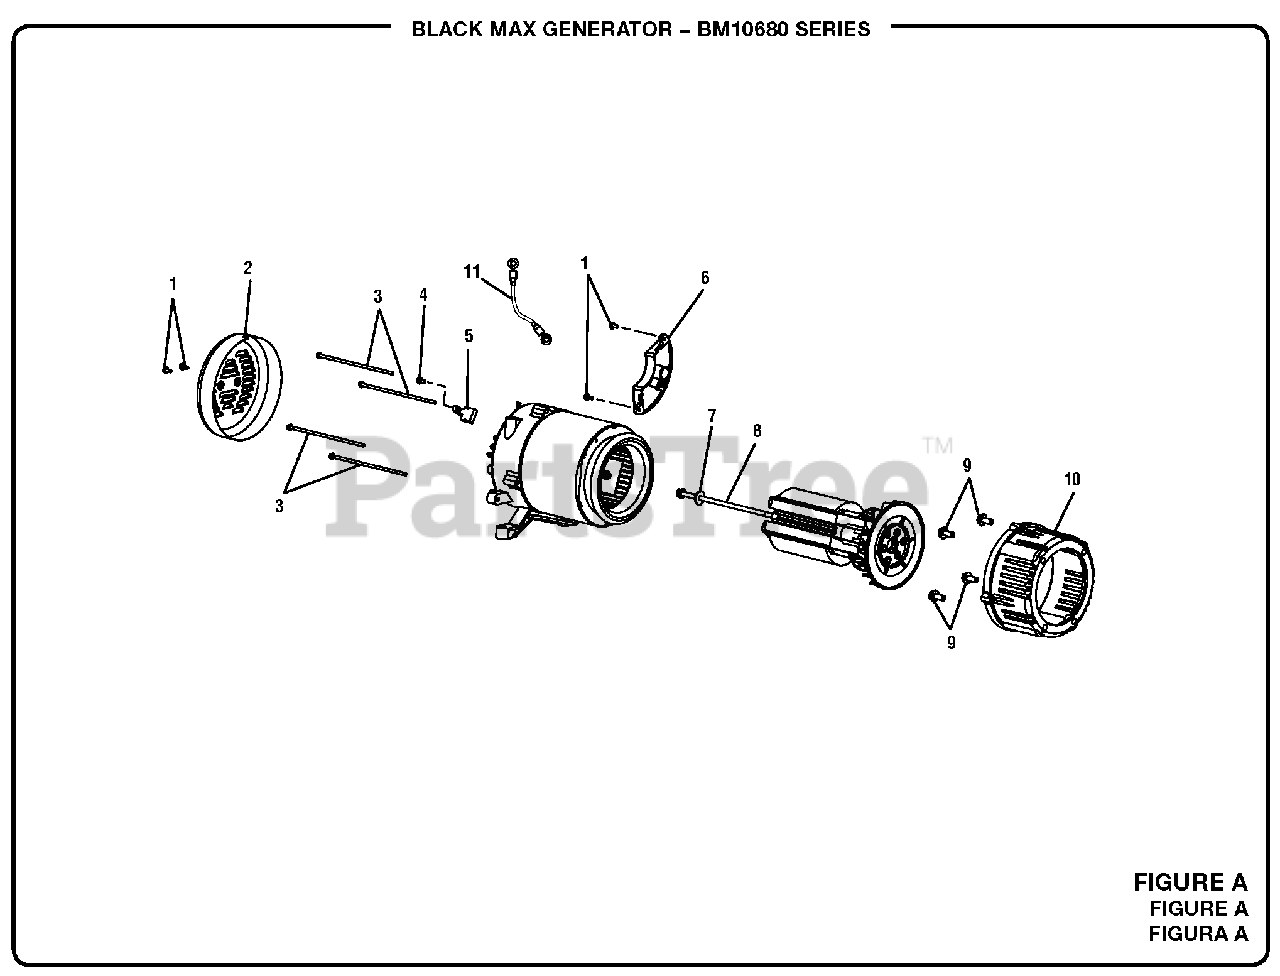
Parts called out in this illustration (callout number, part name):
2	Brush Cover
3	Bolt (1/4-20 x 6 in)
4	Bolt (Brush Assembly)
5	Brush Assembly
6	Automatic Voltage Regulator
7	Lock Washer (5/16 in)
8	Bolt (5/16-24 x 9-1/2 in, Hex Hd)
9	Bolt (3/8-18 x 1-1/4 in)
10	Engine Adapter
11	Bonding Wire
